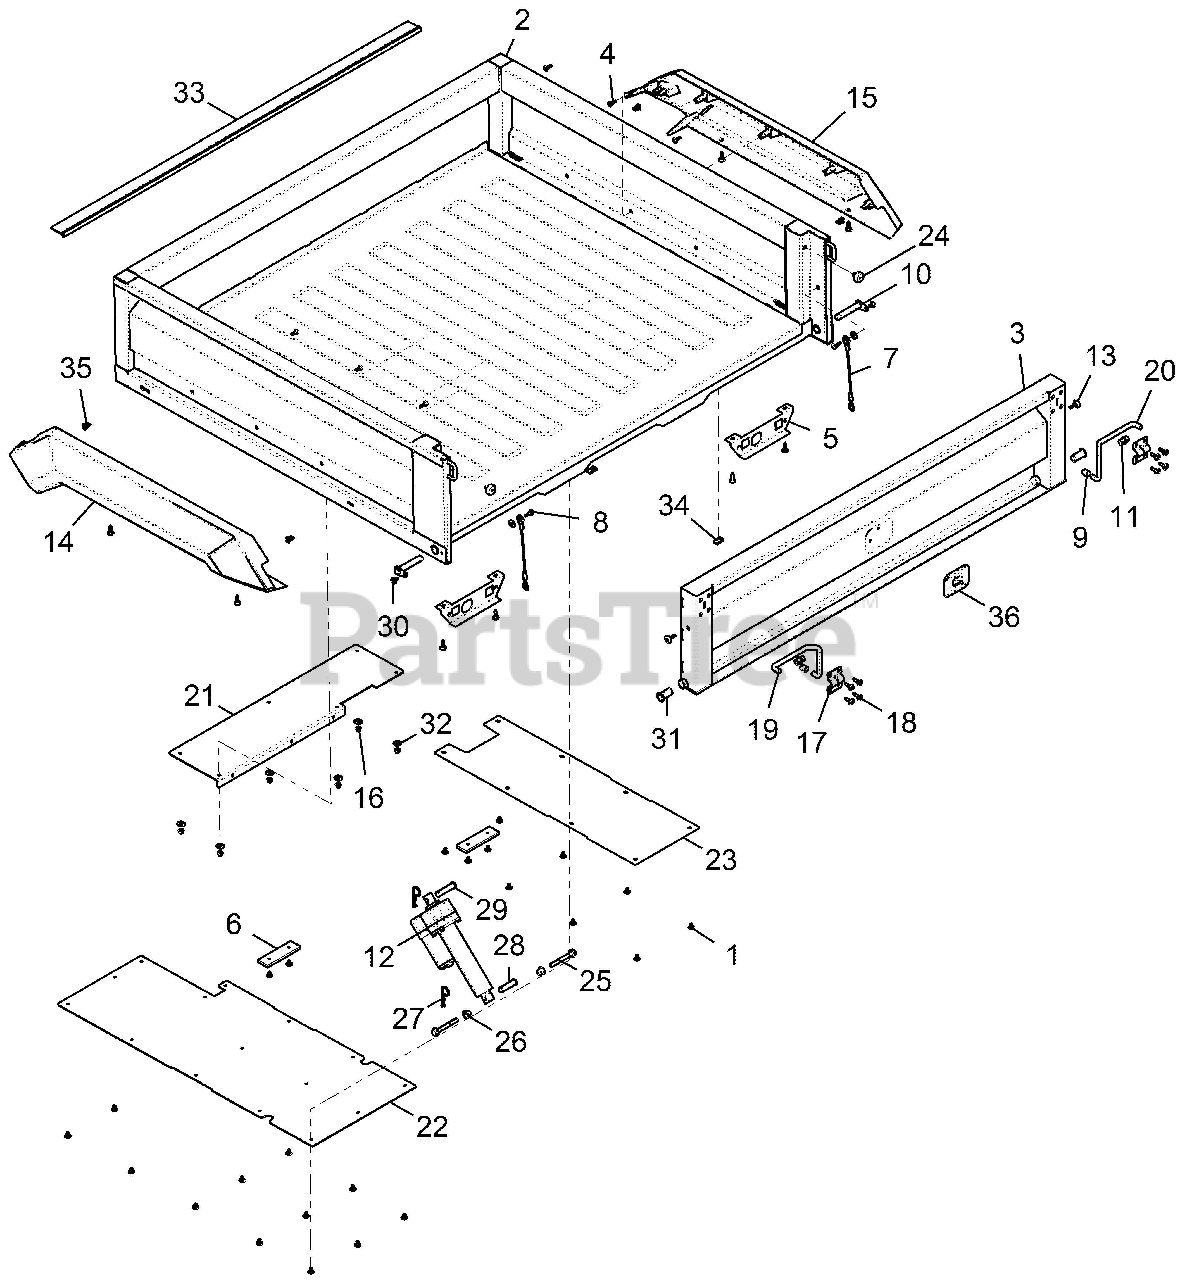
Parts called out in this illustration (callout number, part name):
1	RIVET(50) *
2	BOX, ARNS,GRAVELY RED
3	TAILGATE,ARNS,GRVLY RED
4	SCR-TXPH-#14 X .75 HI-LO RIE
5	BRKT.,TAILLIGHT MOUNT,RED
6	BUMPER-BOX BASE
7	TAILGATE CABLE
8	BLT-SHLDR .188X.188X.25-20
9	CAP, TAILGATE LATCH
10	PIN-TAILGATE MOUNT
11	BUSHING, TAILGATE LATCH
12	ACTUATOR, BOX LIFT
13	SCR-TXTH-M6X1.0X25 RIE,SHDR
14	FLARE-BOX,LH,ARIENS
15	FLARE-BOX,RH,ARIENS
16	NUT-M6 FLANGE,NYLOK
17	BRKT-TAILGATE LATCH
18	SCR-TXTH-M6X1.0X25 RIE
19	ROD, LATCH, LH
20	ROD, LATCH, RH
21	SHIELD, HEAT, EXHAUST, FRONT
22	SHIELD, HEAT, EXHAUST, REAR
23	SHIELD, HEAT EXHAUST MID
24	BUMPER, TAILGATE
25	SCR-HXFL-M10X1.25X80 8.8 ZOD
26	NUT-M10X1.25,FLG,NYLOC-OLIVE D
27	CLIP, HITCH PIN
28	PIN, CLEVIS
29	PIN, CLEVIS BOX LIFT 2"
30	SCR-M6X1X16 TR/TX-M
31	BUSHING, TAILGATE PIVOT PIN
33	TRIM,BOX
34	CLIP-U SPEED NUT
35	CLIP, DASH TRIM METAL
